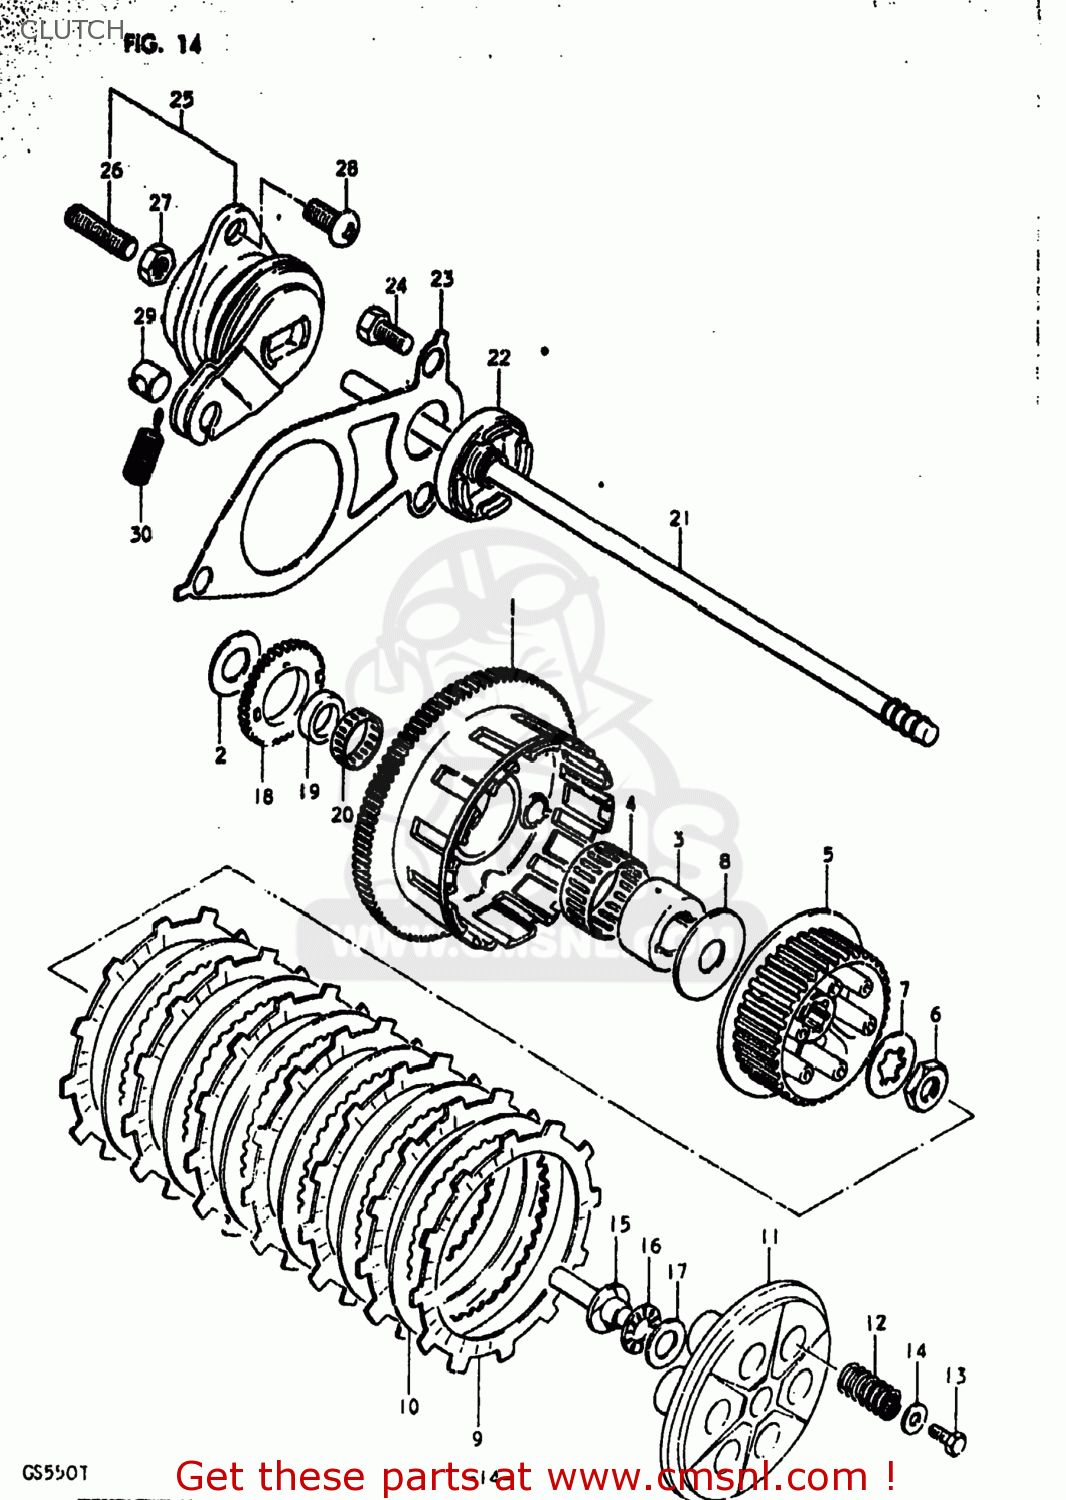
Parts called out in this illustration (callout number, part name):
1	GEAR ASSEMBLY,PRIMARY DRIVE NT:87
2	WASHER
3	SPACER,PRIMARY DRIVEN
5	HUB,CLUTCH SLEEVE
6	NUT
7	WASHER,LOCK
8	WASHER(25X66X3.5)
9	PLATE,CLUTCH DRIVE (NAS)
10	PLATE,CLUTCH DRIVEN (NAS)
11	DISC,CLUTCH PRESSURE
12	SPRING
13	BOLT, UPPER
14	WASHER
15	PIECE,CLUTCH PUSH
16	BEARING(15X28X2)
17	WASHER
18	GEAR,ENG OIL PUMP DRIVE(NT:38)
19	SPACER,OIL PUMP DRIVE GEAR
20	BEARING(36X40X10)
21	ROD,CLUTCH PUSH
22	OIL SEAL
23	PLATE,CLUTCH PUSH ROD
24	BOLT
25	SCREW ASSEMBLY,CLUTCH RELEASE
26	SCREW
27	NUT 6MM
28	SCREW 6X12
29	PIECE,RELEASE ARM END
30	SPRING
